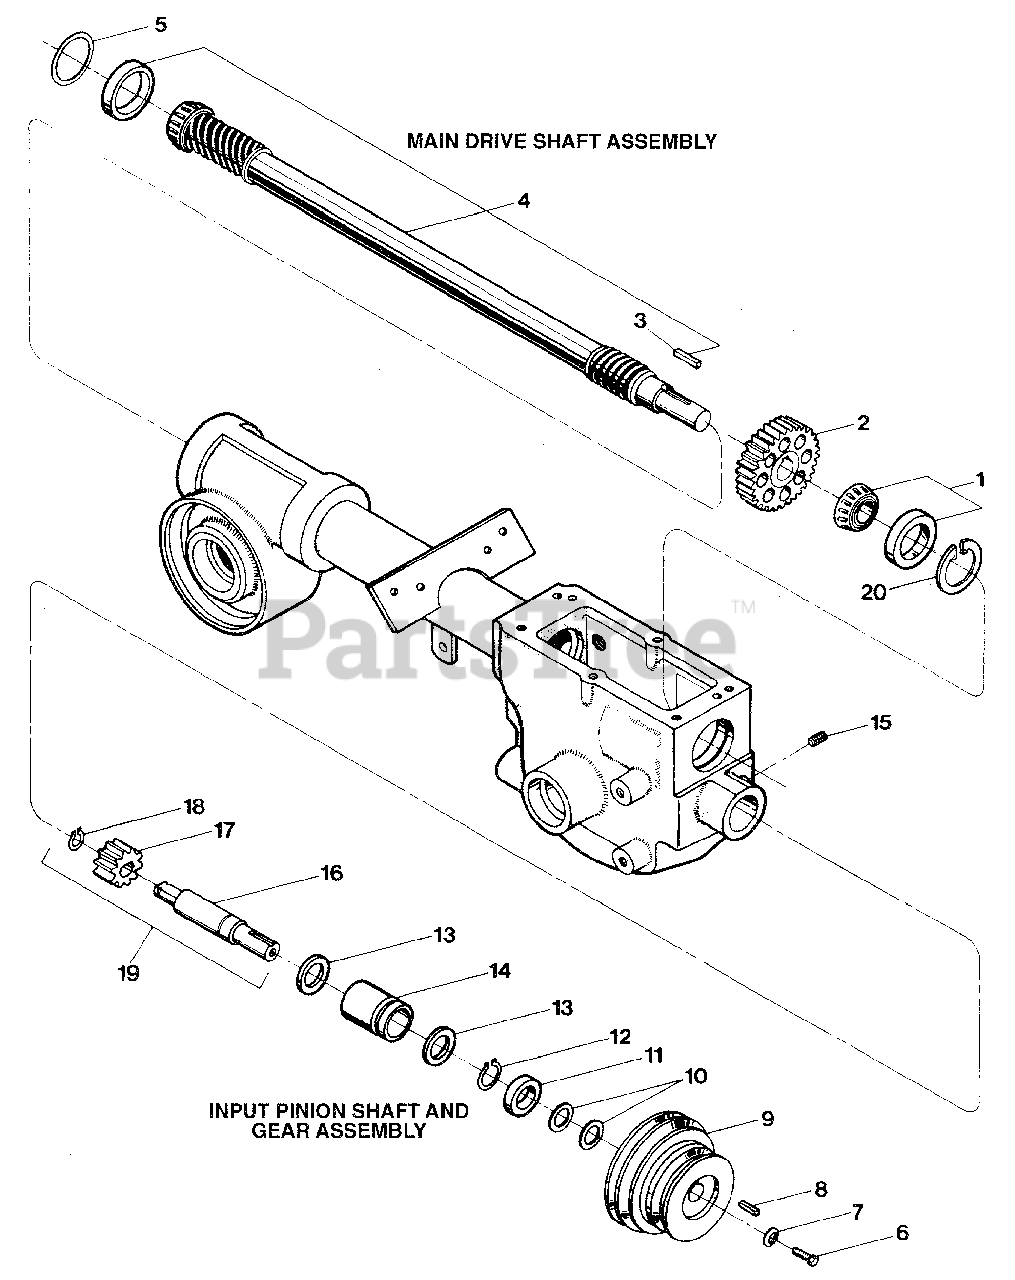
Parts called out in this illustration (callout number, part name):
1	Bearing-tapered roller with race
2	Gear-spur, main drive shaft
3	Key-3116 sq. x 1
4	Drive Shaft
5	Shim-rear bearing cap, .010 thick
5	Shim-same as above, but .030 thick
5	Shim-same as above, but .005 thick
6	Screw-hex hd., 5/16-24 x 3/4
7	Washer-disc spring (concave surface faces pulley)
8	Key-3/16 sq. x 1
9	Pulley-transmission drive
10	Washer-support
11	Oil Seal-input pinion shaft, front.
12	Ring-retaining (snap ring), external
13	Washer-thrust
14	Bushing
15	Set Screw-5/16-18 x 3/8
16	Input Pinion-steel shaft
17	Gear-input pinion
18	Retainer-snap ring, external
19	Pinion Assy
20	Retainer-snap ring, internal
